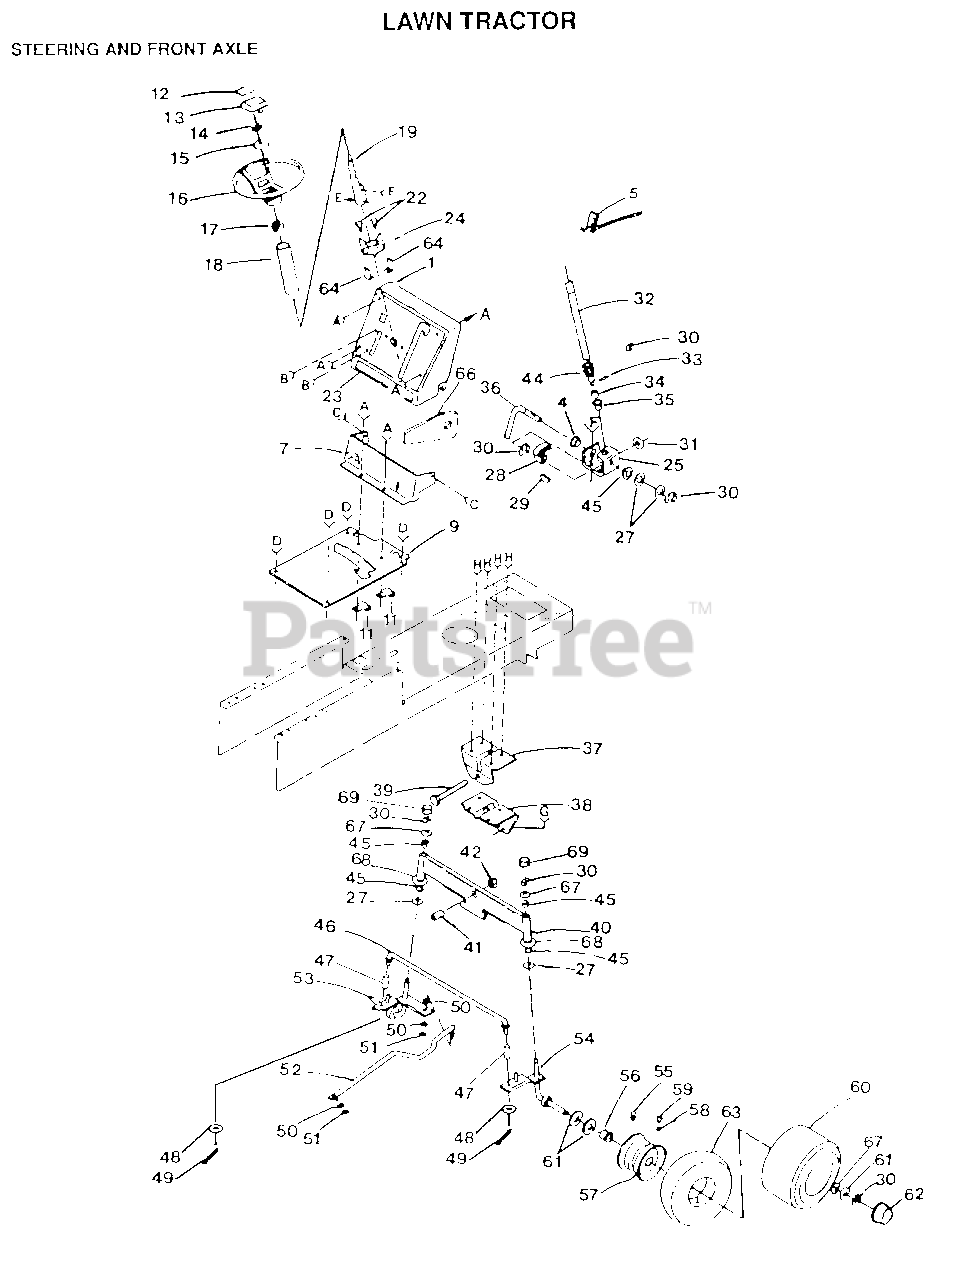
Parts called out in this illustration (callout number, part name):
4	NYLINER T
7	DASH-LOWER LT
11	CLIP T
12	"DECAL,STR WHL T"
13	INSERT-WHEEL LT
15	WASHER
17	ADAPTER LT
19	STEERING SHAFT
24	BUSHING T
27	WASHER .T
28	GEAR.SECTOR.HYT
29	KEY-WOODRUFF LT
30	RING
32	STEERING SHAFT T
34	SHAFT SPACER LT
35	BUSHING
36	ROD STEERING T
37	SUPPORT-SADDL T
38	SUPPORT.SADDLE.FT
39	BOLT LT
41	BEARING
42	"NUT-LOC,FLANGE LT"
44	GEAR PINION T
45	COL. SRTG. BEAR.
48	WASHER
49	COTTER PIN
50	LOCKWASHER
52	LINK-DRAG LT
53	SPINDLE-LH LT
55	FITTING LT
56	"FLANGE, BEARING"
58	VALVE CAP
59	VALVE STEM LT
61	WASHER
62	HUB CAP
63	TUBE.5.3/4.5/6
64	RETAINER T
67	WASHER
68	WASHER
69	CAP
